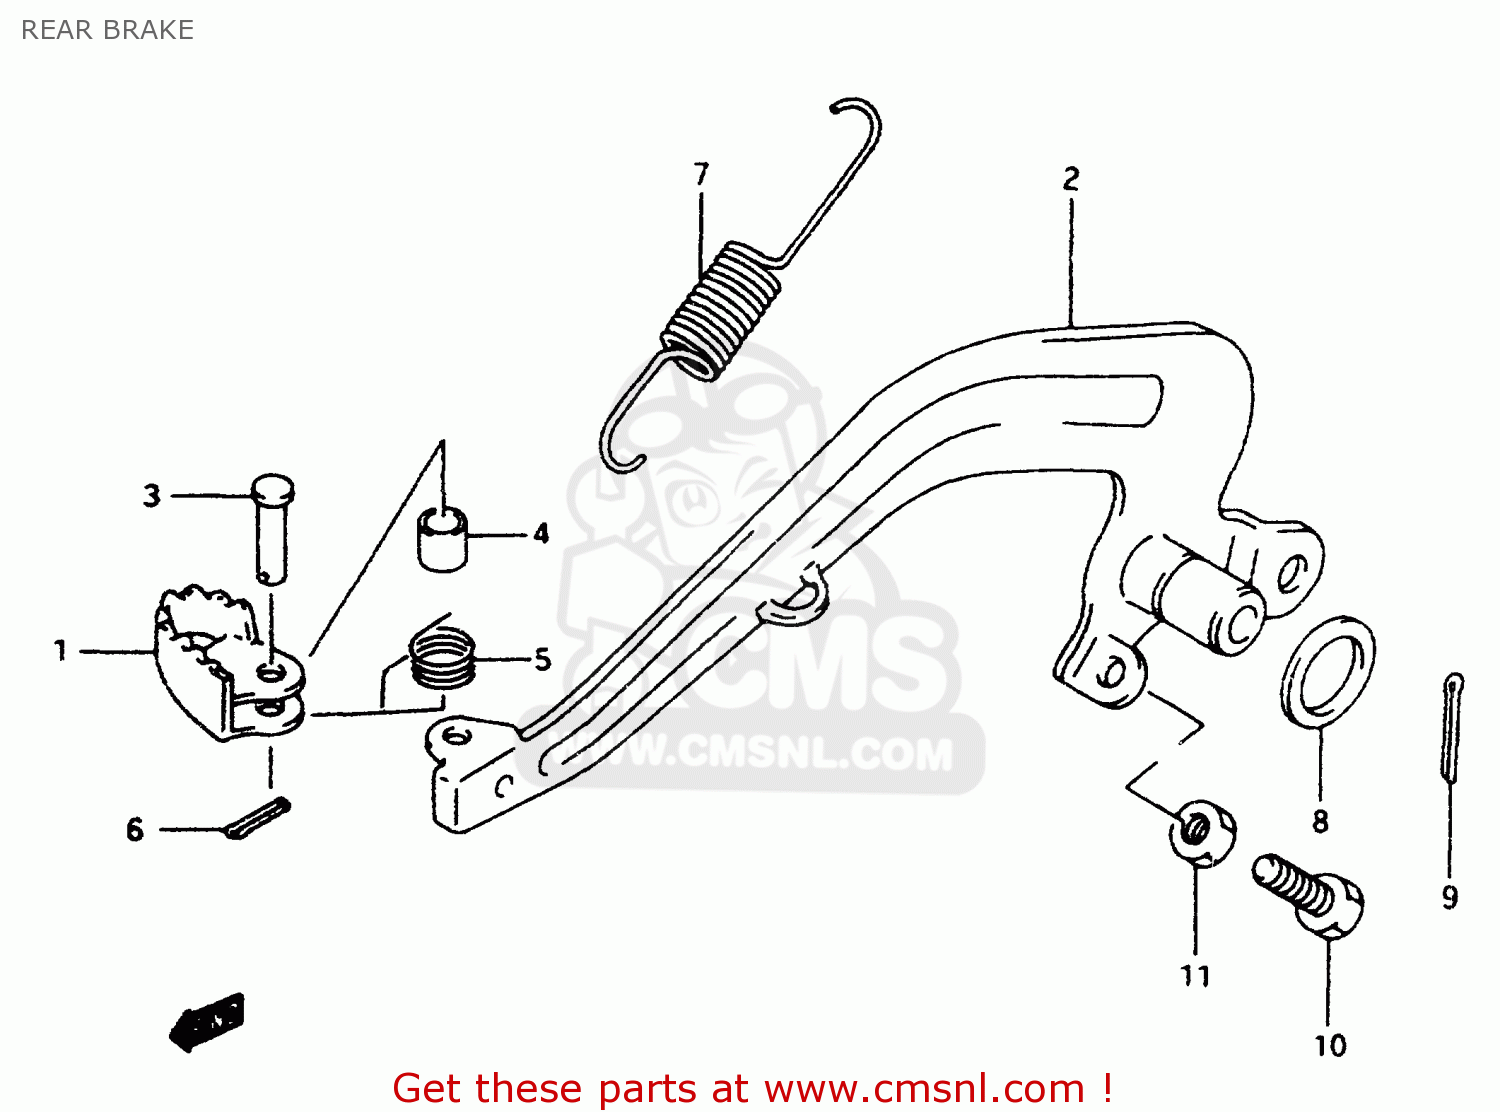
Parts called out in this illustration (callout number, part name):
1	PEDAL,BRAKE
2	ARM,BRAKE PEDAL
3	PIN
4	SPACER(6.5X9X6.5)
5	SPRING
6	PIN
7	SPRING
8	WASHER(15.5X26X2.3)
9	PIN, COTTER
10	SCREW(6X23)
11	NUT 6MM
